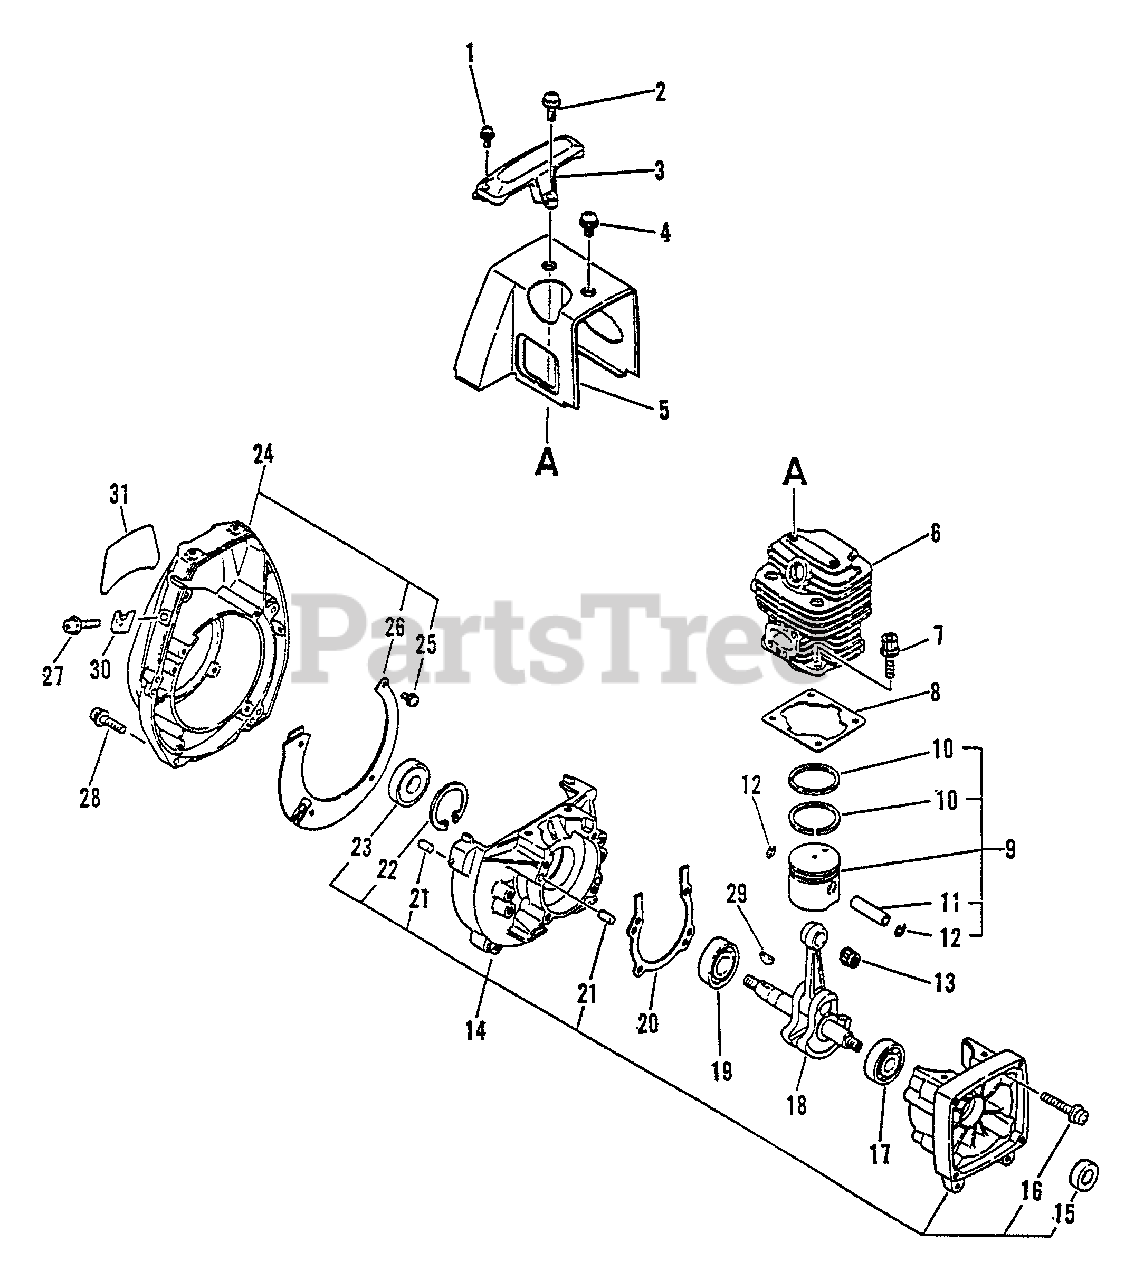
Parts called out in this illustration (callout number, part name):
1	SCREW 4×14
2	SCREW 5×16
3	GUARD, TOP
4	SCREW 5×10
5	COVER, ENGINE
6	CYLINDER
7	BOLT 5×20
8	GASKET, CYLINDER
9	PISTON KIT
10	RING, PISTON
11	PIN, PISTON
12	RING, RETAINING
13	BEARING, NEEDLE 9
14	CRANKCASE KIT
15	SEAL, OIL 12
16	SCREW 5×30
17	BEARING, BALL - 6201 C3
18	CRANKSHAFT
19	BEARING, BALL 6202
20	GASKET, CRANKCASE
21	PIN, LOCATING 5×10
22	RING, SNAP 35
23	SEAL, OIL
24	FAN CASE ASSY
25	SCREW 4×8
26	PLATE, GUIDE
27	SCREW 4×10
28	SCREW 5×25
30	HOLDER, CABLE
31	LABEL - MODEL
31	GASKET KIT
31	GASKET, CRANKCASE
31	GASKET, CYLINDER
31	GASKET, INTAKE
31	GASKET
31	GASKET, MUFFLER
31	GASKET, EXHAUST
